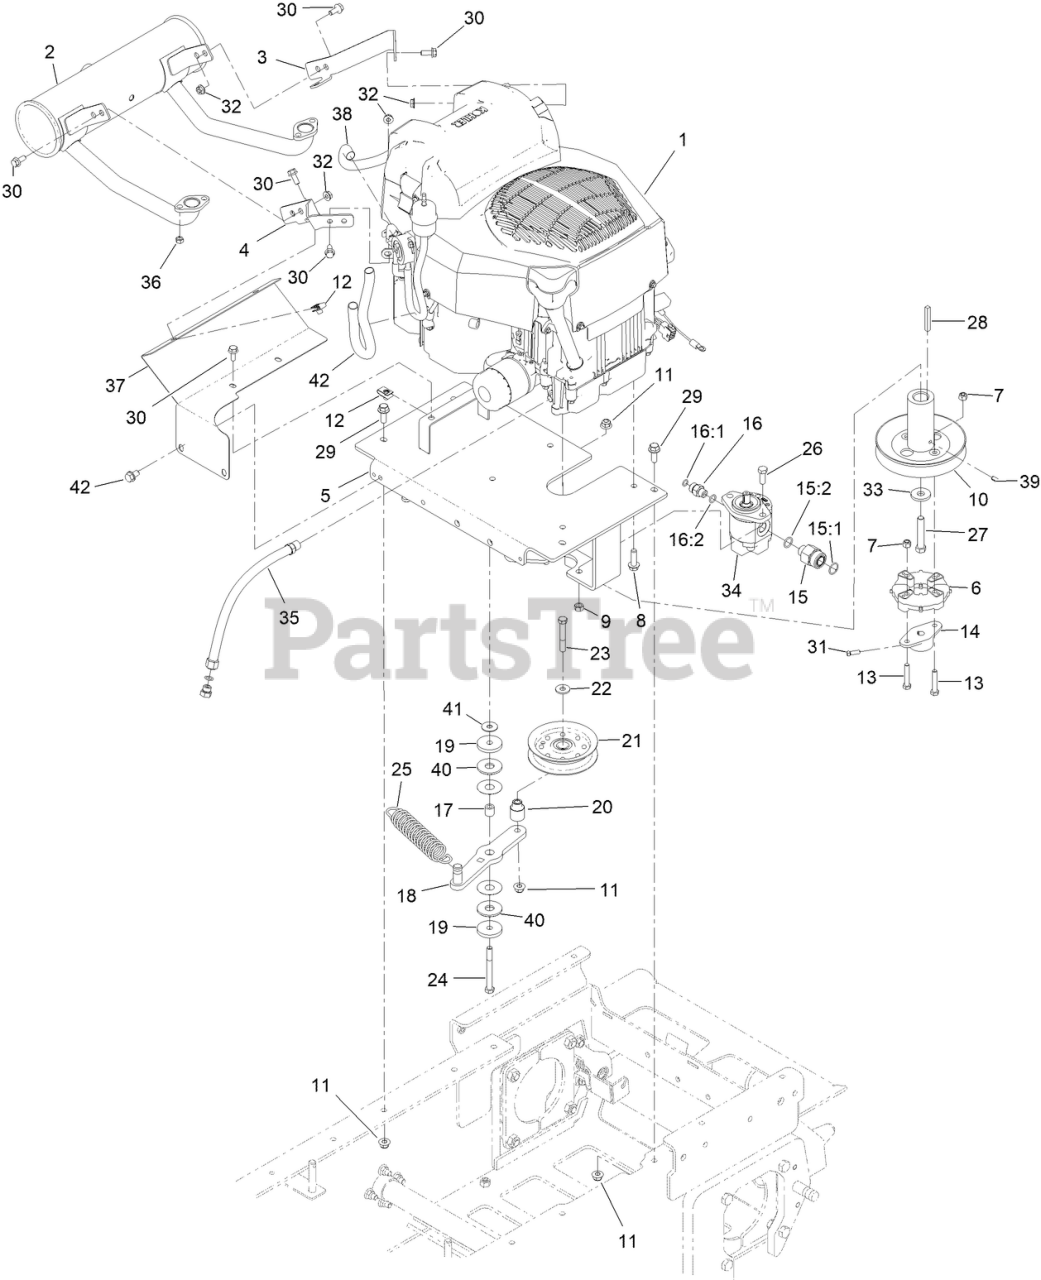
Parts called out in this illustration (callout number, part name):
1	ENGINE-KOHLER, ZT740 [SERVICE]
2	MUFFLER-KOHLER
3	BRACKET-MUFFLER
4	BRACKET-MUFFLER
5	ENGINE PLATE ASM (WELDED)
6	COUPLER-RUBBER
7	NUT-LOCK, NI
8	SCREW-THD
9	NUT-HEX
10	PULLEY-ENGINE
11	NUT-HF, NI
12	NUT-CLIP, U
13	SCREW-HH
14	HUB-PUMP
15	FITTING-STRAIGHT
15:2	O-RING
16	FITTING-STRAIGHT
16:1	O-RING
16:2	O-RING
17	SPACER-KNOB, SEAT
18	IDLER ARM ASM (WELDED)
19	WASHER-PLAIN
20	BUSHING-IDLER
22	WASHER-HARDENED
23	SCREW-HH
24	SCREW-HH
25	SPRING-EXTENSION
26	SCREW-HH
27	SCREW-HH
29	SCREW-HHF
30	SCREW-HHF
31	SCREW-SQH
32	NUT-FLANGE
33	WASHER-FLAT
34	PUMP-GEAR
35	HOSE-DRAIN, OIL
37	SHIELD-MANIFOLD
38	SLEEVE-THERMAL
39	PIN-ROLL
40	WASHER-FRICTION, COMPOSITE
41	WASHER-FLAT
42	SCREW-HHFTF
